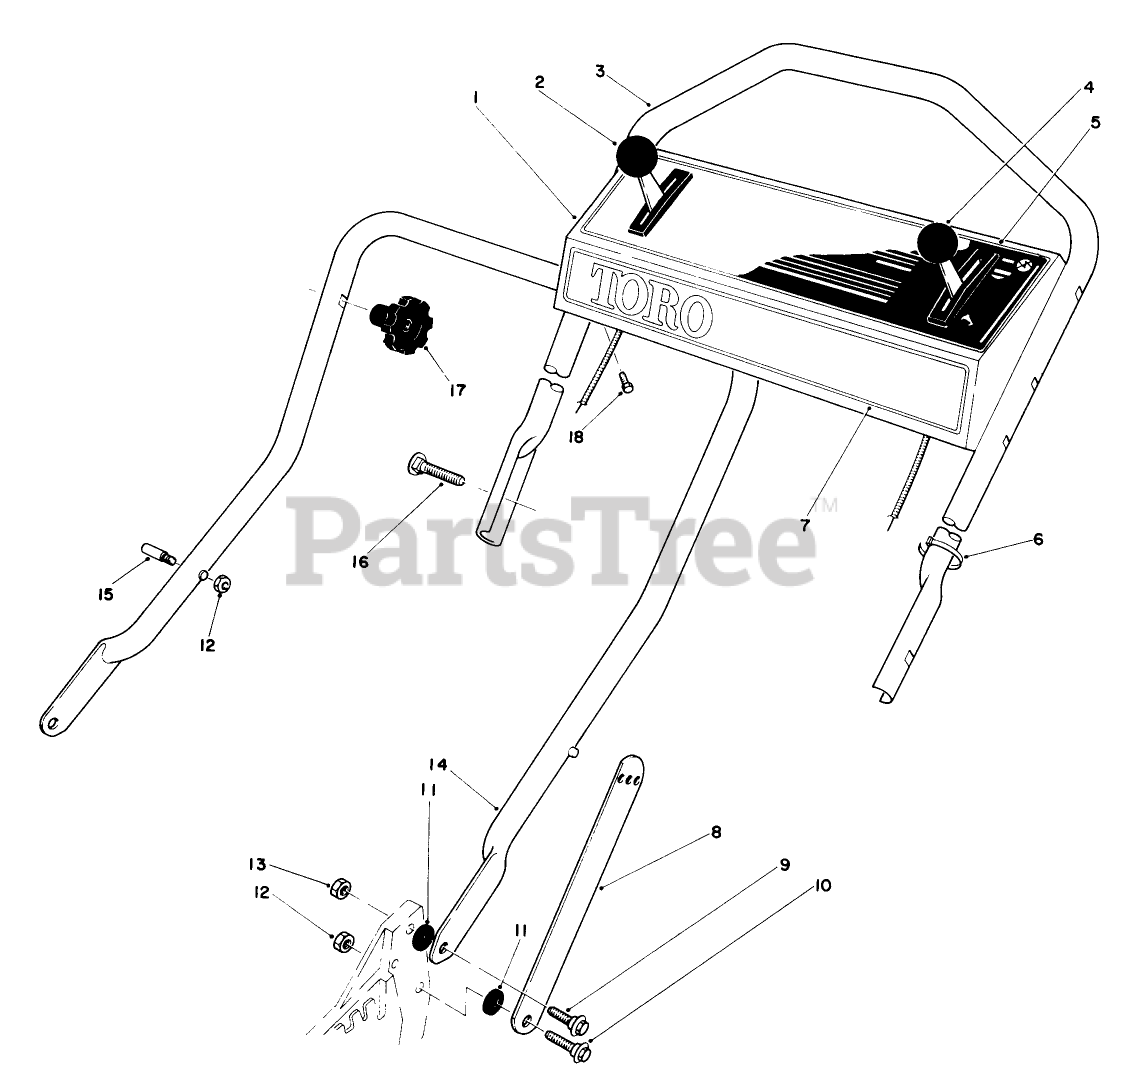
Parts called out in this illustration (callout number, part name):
2	GROUND SPEED CONTROL
4	SERVICE THROTTLE CONTRO
6	BOWDEN CLIP
9	SCREW-SHOULDER
10	SCREW-SHOULDER
11	SPACER
12	NUT-LOCK, NI
13	NUT-LOCK, NI
15	HANDLE PIN
18	SCREW-HWHTF
